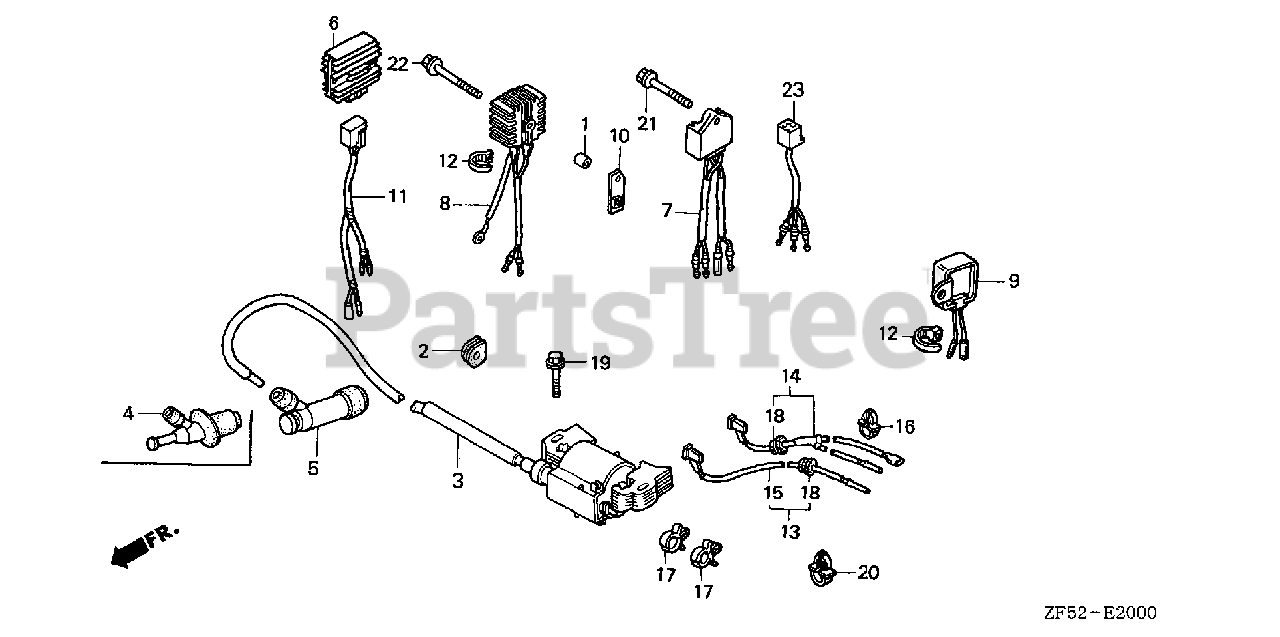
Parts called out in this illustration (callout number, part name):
3	COIL ASSY., IGNITION
5	CAP ASSY., NOISE SUPPRESSOR
8	RECTIFIER ASSY., SILICON
10	BRACKET, RECTIFIER
12	BAND B1, WIRE
13	WIRE, STOP SWITCH (AYP)
18	GROMMET, WIRE CORD
19	BOLT, FLANGE (6X28) (CT200)
22	BOLT, FLANGE (6X32)
23	SUB-WIRE HARNESS ASSY. (AYP)
